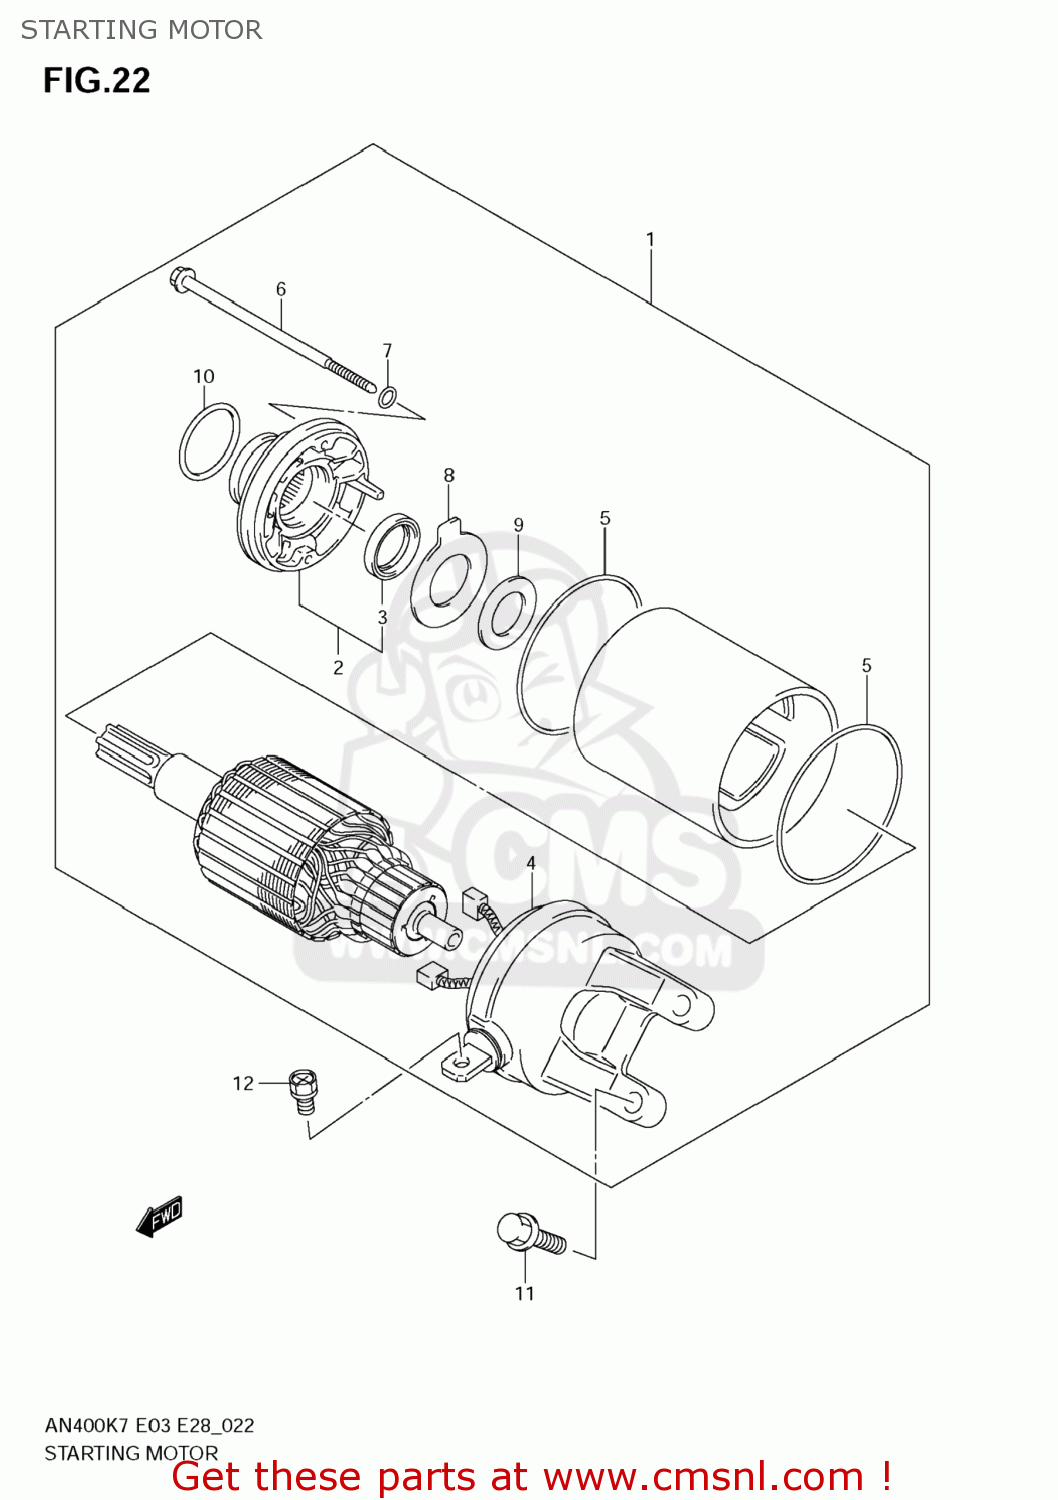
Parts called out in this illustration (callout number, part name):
1	MOTOR ASSY,STARTING
2	BRACKET
3	SEAL,OIL
4	FRAME ASSY,COMMUTATOR END
5	O RING
6	BOLT
7	O RING
8	PLATE,LOCK
9	SHIM
10	O RING(D:3,ID:24.5)
11	BOLT(6X20)
12	SCREW(5X8)
